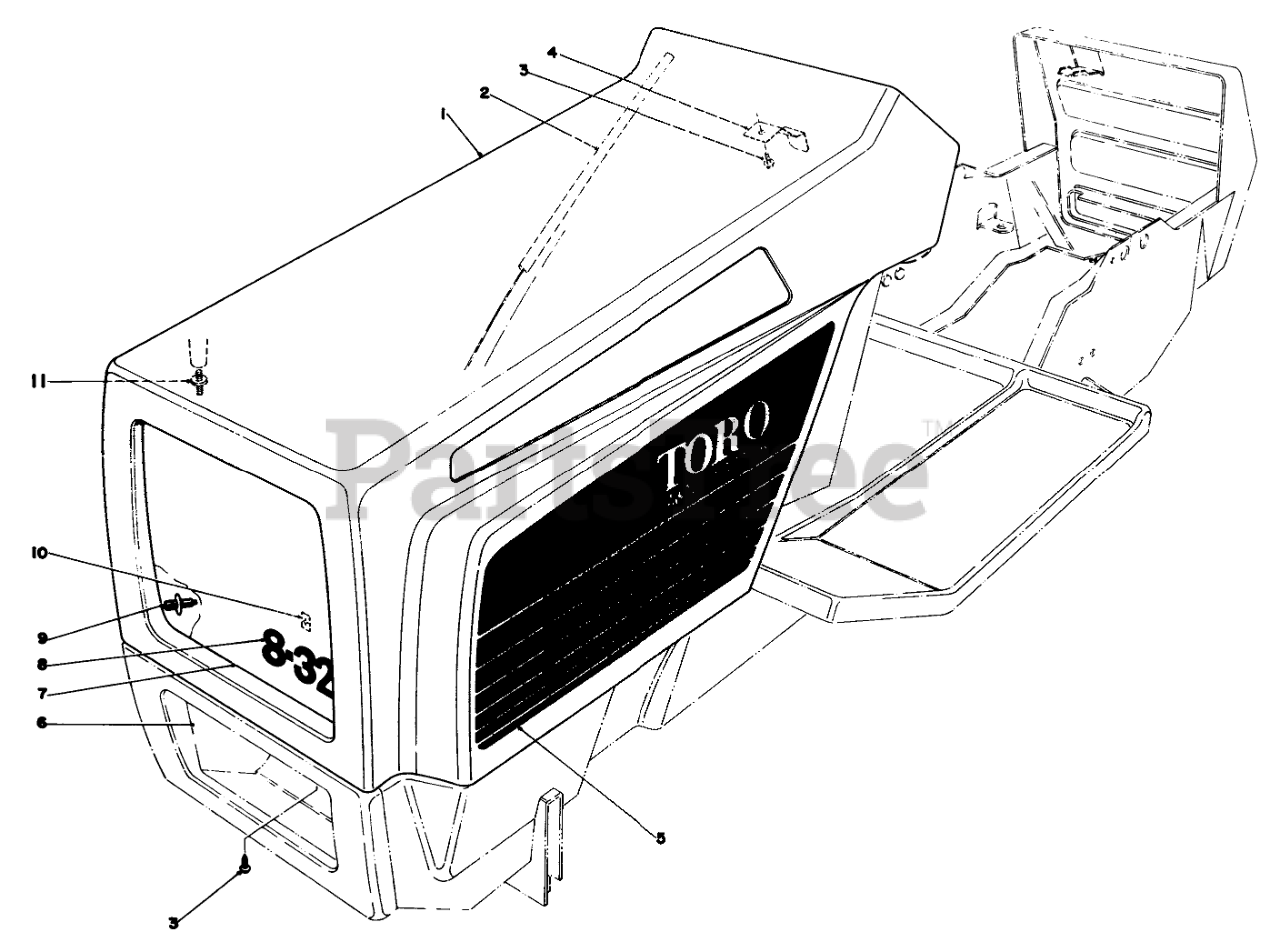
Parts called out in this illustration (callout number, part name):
1	Hood (Incl. Ref. #9 & 11)
2	RUBBER EXT SEAL
3	SCREW-HWHTF
4	SPRING LATCH
5	Decal-Hood L.H.
6	LOWER GRILLE
7	HOOD GRILLE
8	Nameplate Grille
9	HINGE BRKT STUD
11	Stud Hood Duct
